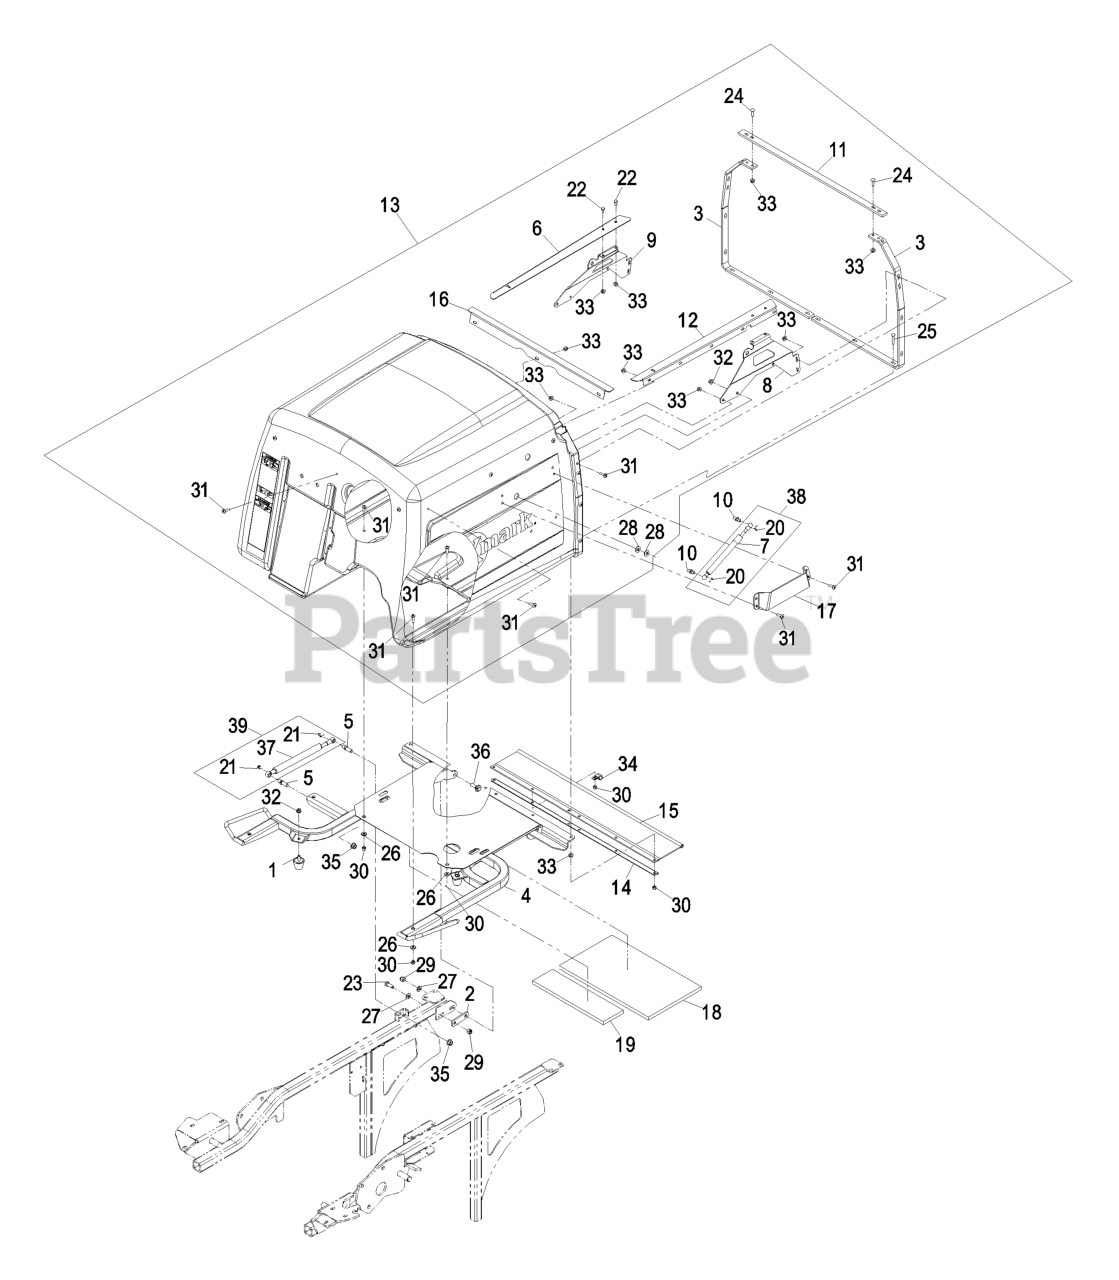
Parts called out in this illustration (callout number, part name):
1	BUMPER-RUBBER
2	ARM-LIFT, DECK
3	REINFORCEMENT-HOPPER
5	STUD-BALL
6	ANGLE-SCREEN TRACK, RH
7	SHOCK-GAS TENSION
8	BRACE-DOOR PIVOT, LH
9	BRACE-DOOR PIVOT, RH
10	STUD-BALL
11	BRACKET-FRAME CONNECT
12	ANGLE-SCREEN TRACK, LH
13	ASM,HOPPER
14	CHANNEL-FRAME, HOPPER
15	DEFLECTOR-GRASS
16	CHANNEL-SCREEN, FRONT
17	Guard, Damper
18	INSULATION-FOAM PAD, REAR
19	INSULATION-FOAM PAD, FRON
20	CLIP-RETAINER
21	CLIP-RETAINER
22	SCREW-HH
23	SCREW-HH
24	SCREW-CARR
25	SCREW-CARR
26	WASHER-FLAT
27	WASHER-FLAT
28	WASHER-FLAT
29	NUT-LOCK, NI
30	NUT-LOCK, NI
31	SCREW-PTH
34	CLIP-LOOM
36	SCREW-SHOULDER, HWH
37	SHOCK-COMPRESSION, GAS
38	DAMPER KIT
39	DAMPER KIT
